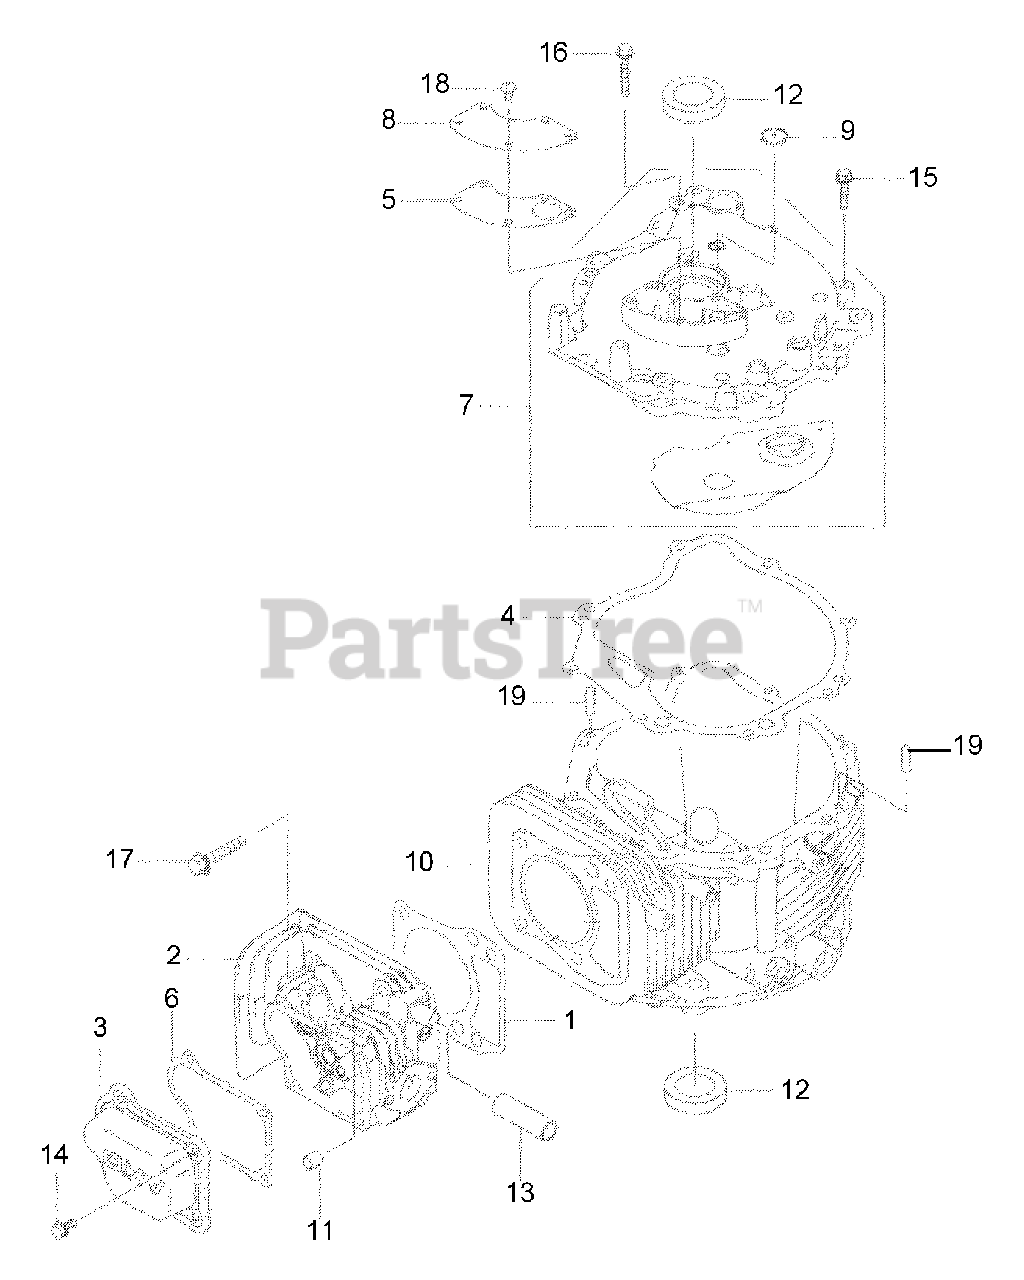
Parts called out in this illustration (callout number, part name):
1	Head Gasket
2	Cylinder Head
3	Rocker Case
4	Cover Gasket
5	Breather Gasket
6	Rocker Case Gasket
7	Cover-Complete
8	Breather Cover
9	Breather Valve
10	Crankcase-Complete
13	Tube, 12x16x49
14	Flanged Bolt
15	Flanged Bolt
16	Flanged Bolt
17	Flanged Bolt
